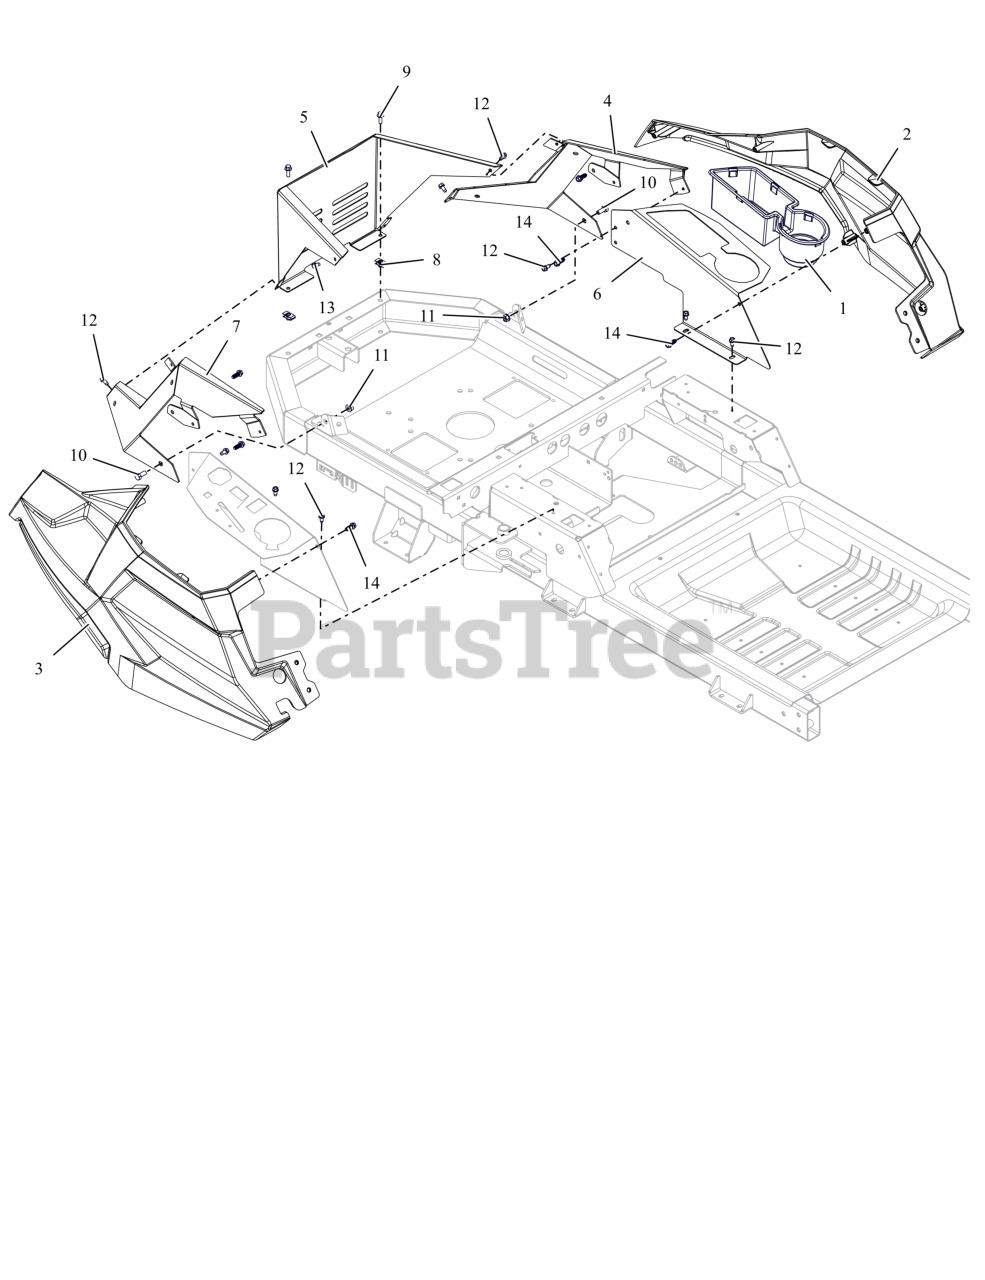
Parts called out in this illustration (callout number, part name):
1	INSERT, CUP/STORAGE HOLDER
2	FENDER, LH
3	FENDER, RH
4	WRAP, REAR - LH (RED)
5	WRAP, REAR (BLACK)
6	PANEL, CUP HOLDER (RED)
7	WRAP, REAR - RH (RED)
8	NUT-RTNR .25-20X.56
9	BLT,HEX-FLG .25-20X.75 G5 BFP
10	BLT,HEX .31-18X.75 G5 ZCC
11	NUT-LK-TOP-FLG .312-18 GF ZCC
12	SCR-TAP .25-20X.50 HWH ZCC
13	SCR,TAP .25-20X.375 HWH TR ZCC
14	SCR-.312X.75 #14H H/W/H H/L CZ
